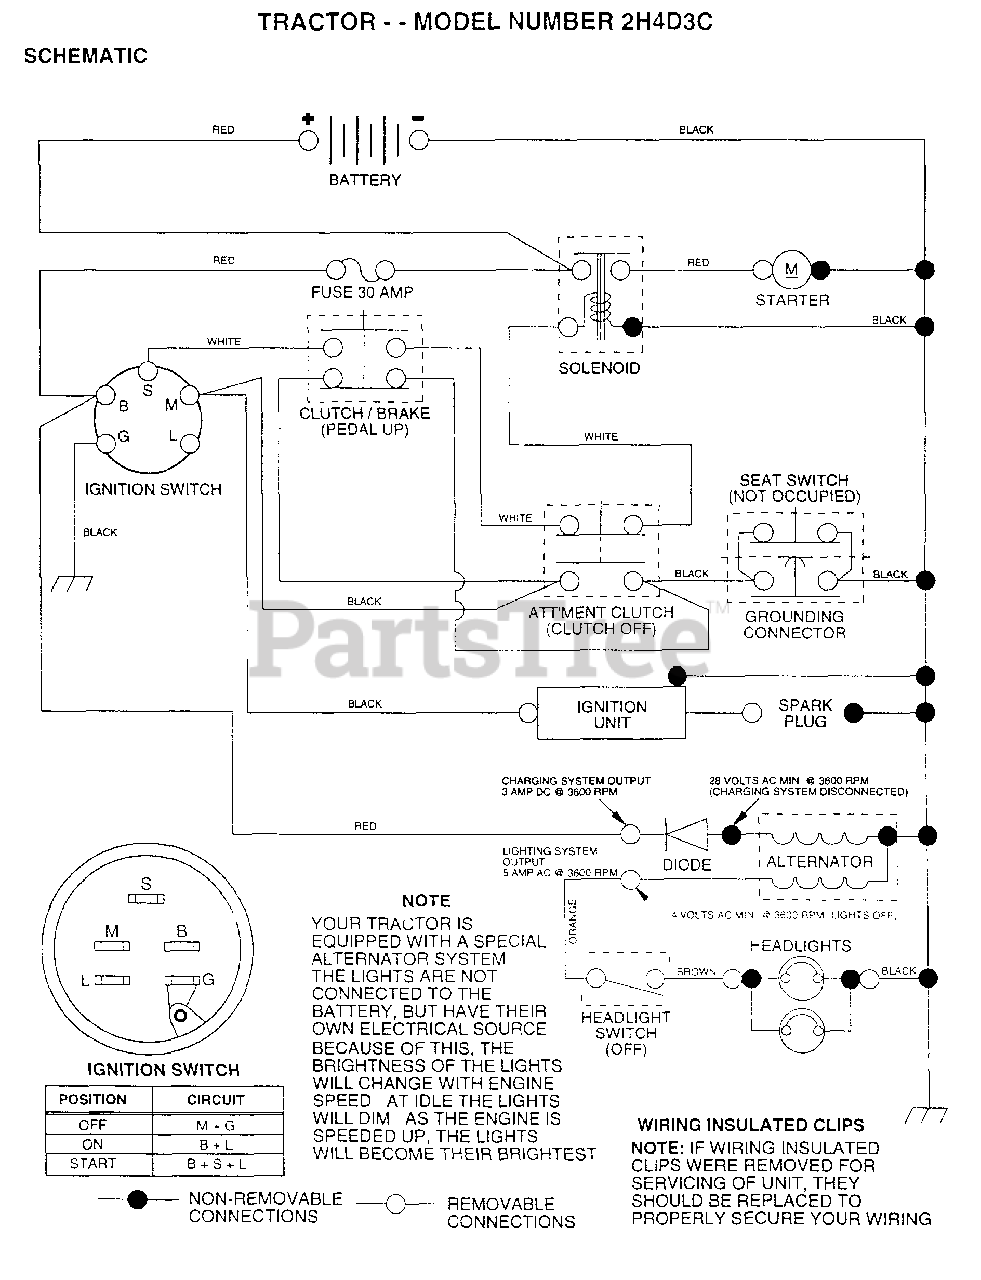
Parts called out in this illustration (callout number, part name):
2	BRACKET PVT SEAT
3	BOLT
4	WASHER PM
5	CLIP.PUSH-IN.HING
6	NUT
7	SPRING COMPRESSIO
8	SCREW GTV
9	WASHER
12	BRKT SWITCH
13	BUSHING
15	SPLIT SPACER
16	SPRING
21	"BOLT,SHOULDER"
22	NUT
23	BOLT
24	WASHER
25	"BOLT,SHOULDER"
26	LOCKWASHER
